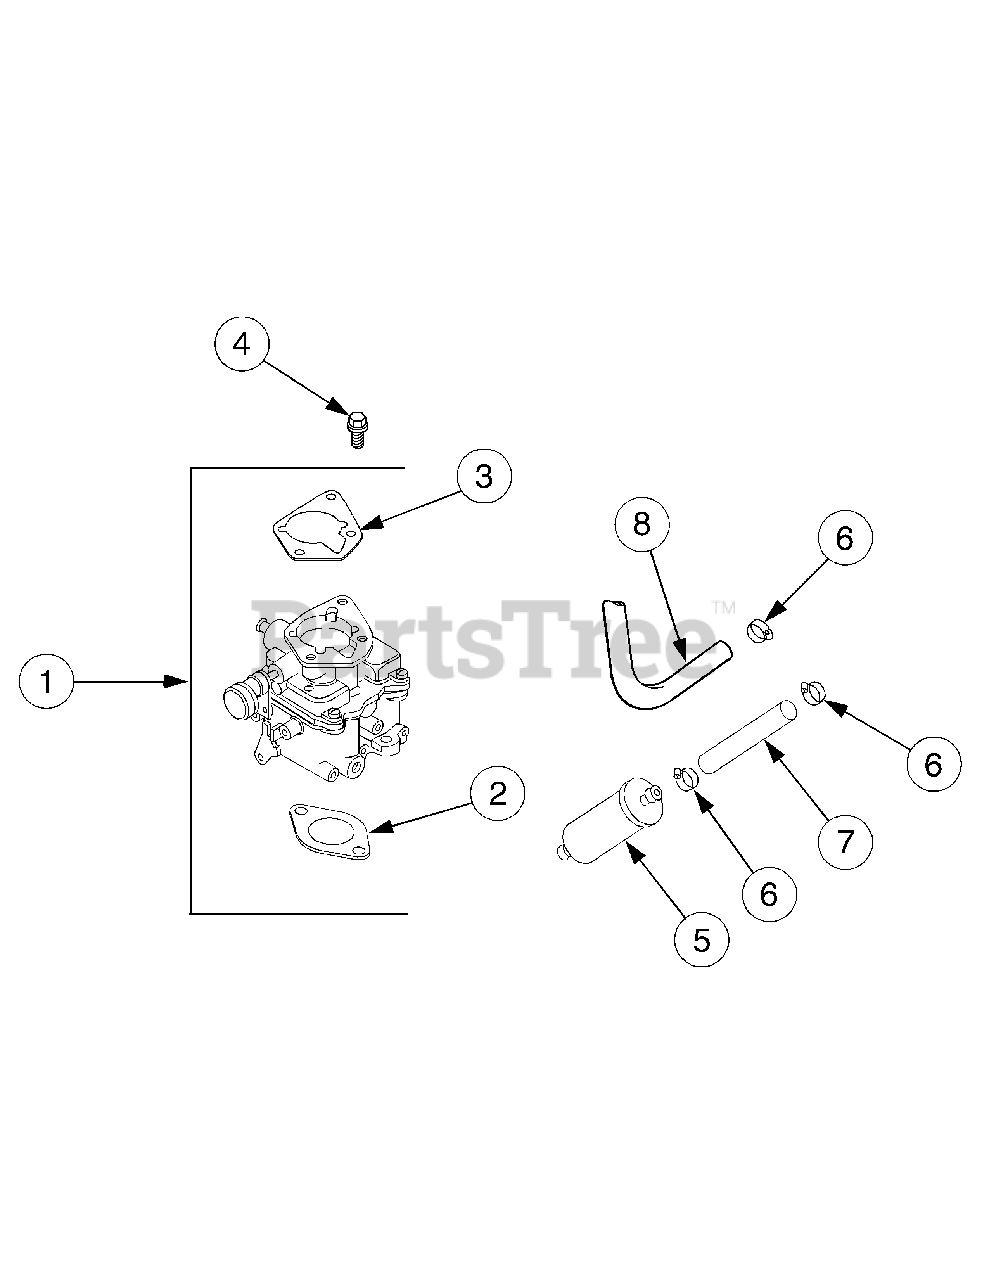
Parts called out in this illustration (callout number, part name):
1	Kit, Carburetor w/Gasket (Includes 2,3)
2	Gasket, Air Cleaner Base
3	Gasket, Carburetor
4	Screw, Hex Flange, M6 x 1.0 x 25
5	Filter, Fuel
6	Clamp, Hose
7	Line, Fuel 10" (Carb to Filter)
8	Line, Fuel 11" (Carb to Pump)
